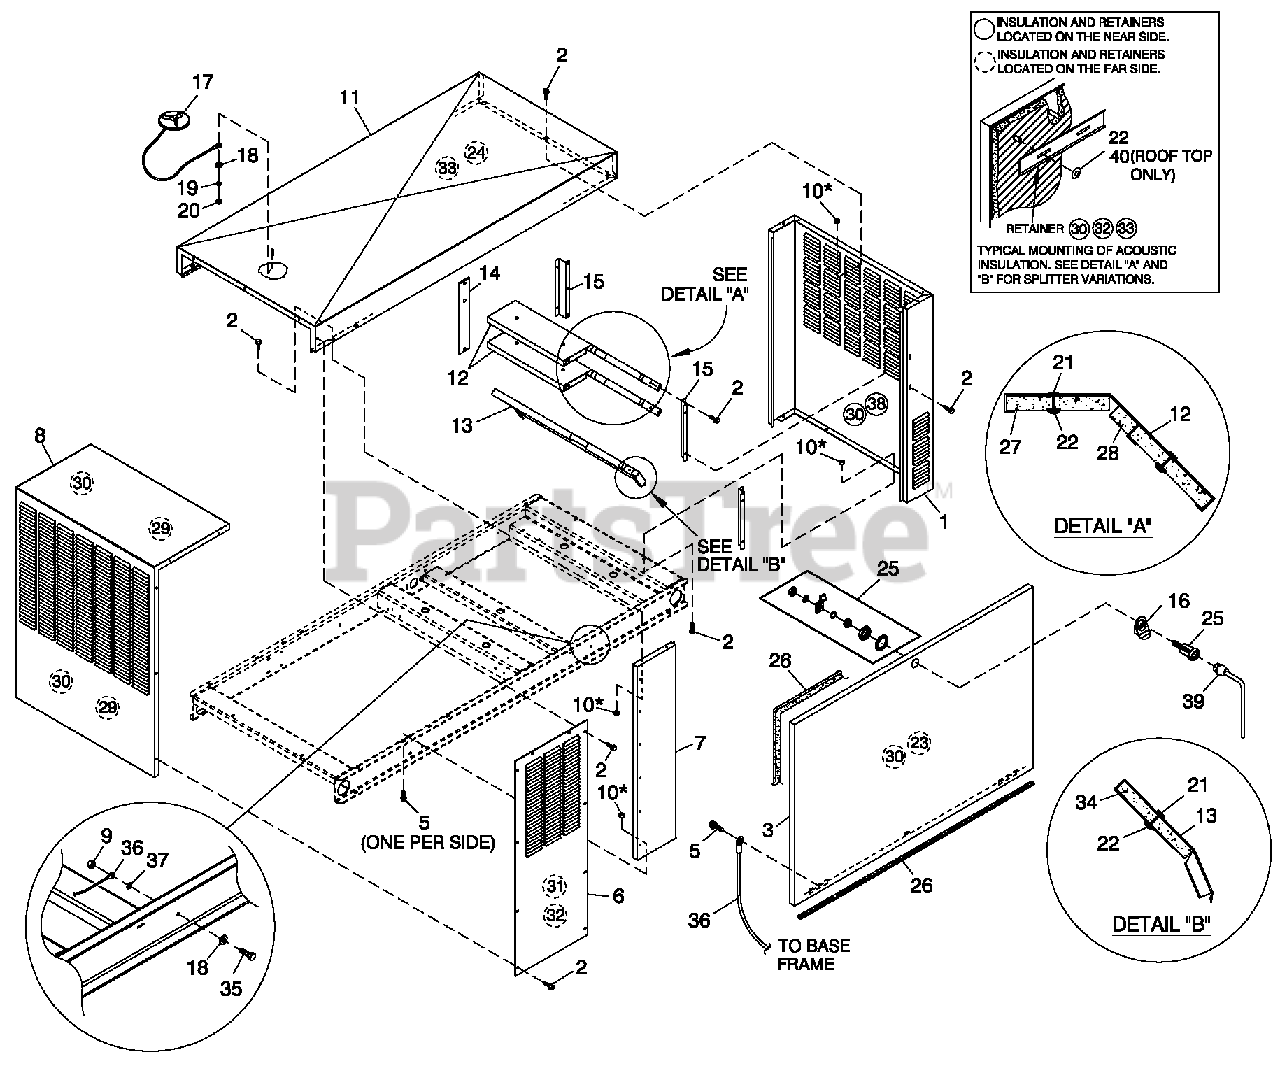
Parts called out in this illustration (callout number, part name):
1	REAR WRAP C2 CPL
2	SCREW THF M6-1 X 16 N WA Z/JS
3	DOOR C2
4	RIVET POP .1875X .450SS
5	SCREW TH-FRM M6 W/CAP SHKPRF W
6	DISCHARGE DUCT LH & RH SIDE C2
7	FRONT CORNERS C2
8	DISCHARGE CENTER DUCT C2
9	NUT HEX M6X 1.0 G8YEL CHR
10	NUT HEX LOCK M6-1.0 SS NY INS
11	ROOF C2
12	SLITTER C4
13	SPLITTER LOWER C4
14	SPLITTER STINGER C2
15	SUPPORT SPLITTER LH C2
16	TAB PULL
17	ASSEMBLY COVER ACCESS
18	WASHER FLAT 1/4-M6 ZINC
19	WASHER LOCK M6-1/4
20	NUT HEX 1/4-20 STEEL
21	INSULATION RETAINMENT HANGER
22	WASHER SELF LOCKING DOME #4-40
23	INSULATION DOOR C2
24	INSULATION ROOFTOP
25	VISE-ACTION LATCH SLOTTED CIR
26	GASKET EXTRUDED TRIM (328" LG)
27	INSULATION SPLITTER
28	INSULATION SPLITTER
29	INSULATION DUCT
30	RETAINER INSULATION (820)
31	INSULATION DUCT SIDES
32	RETAINER INSULATION (450)
33	RETAINER INSULATION (740)
34	INSULATION LOWER SPLITTER
35	SCREW HHC M6-1.0X 20 G8.8
36	ASSY WIRE 14 AWG 34.8" GRN/YEL
37	WASHER SHAKEPROOF INT1/4
38	INSULATION REAR WRAP
39	KEY VISE-ACTION LATCH SLOT CIR
40	WASHER SELF LOCKING DOME #8-32
